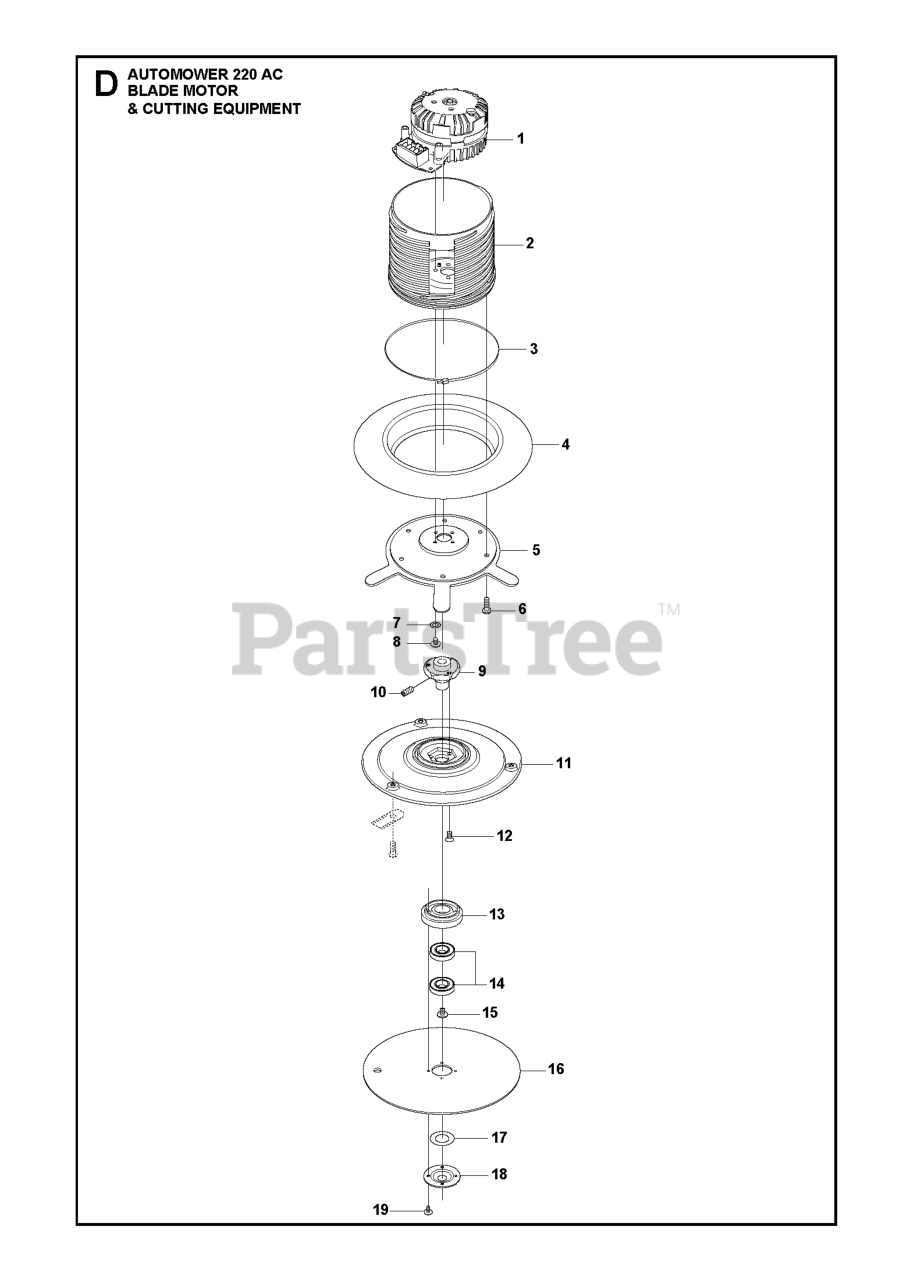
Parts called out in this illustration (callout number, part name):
2	MOTOR BOWL CUTTING MOTOR
2	HOLDER
6	SCREW
6	SCREW 14MM
9	HUB CUTTING DISC
11	BLADE DISC
12	SCREW TORX M4X8 8.8 NYLON PATC
14	BALL BEARING 2 RS,TIGHT CLEAR
14	BALL BEARING BALL BEARING 535
16	PLATE SKID
18	COVER SKID PLATE
19	SCREW SILVER 10MM
